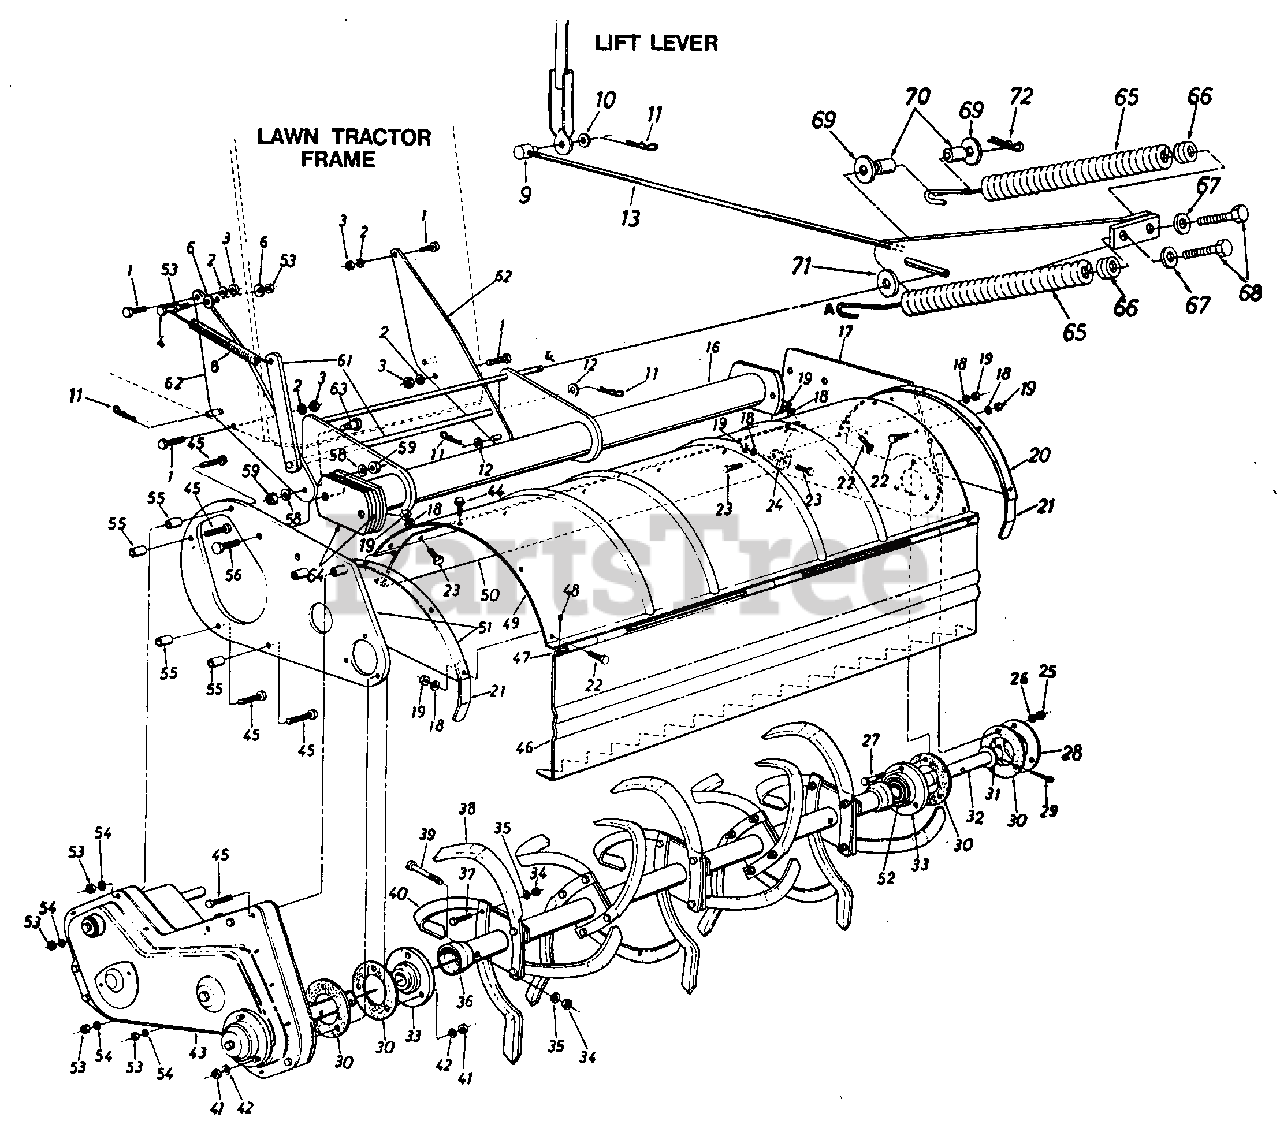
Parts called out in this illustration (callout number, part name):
1	Hex Bolt 3/8-24 x .88" Lg.
2	L-Wash. 3/8" I.D.-H.D.
3	Hex Nut 3/8-24 Thd.
4	Hex Bolt 1/4-20 x 1.25" Lg.
6	Bell-Wash. 1/4" I.D.
8	Ext. Spring 7.75" Lg.
9	Adjustment Ferrule 1/2-13 Thd.
10	Fl-Wash. .64" I.D. x 1.24" O.D. x .06"
11	Intern. Cotter Pin 1/2" Dia.
12	Fl-Wash 51" I.D. x 1.0" O.D. x .06"
16	Pivot Bracket Assembly
19	Hex Nut 5/16-24 Thd.
23	Hex Bolt 5/16-24 x .62" Lg.
24	Chute Pivot Bracket
25	Hex L-Nut 5/16-18 Thd.
27	Hex Bolt 5/16-18 x 1" Lg. (Grade 5)
30	Gasket for Brg. Housing
31	Fl-Wash. 1.25" I.D. x 2.0" O.D. x .06"
32	Tine Shaft 1.25" Dia. x 6.25" Lg.
33	Bearing Housing w/Bearing
43	Chain Case Ass'y. Comp.
44	Hex TT-Tap Scr. 5/16-18 x .62" Lg.
45	Hex Bolt 1/4-20 x 2.75" Lg.
48	Cotter Pin 1/8" Dia. x 1" Lg.
53	Hex Nut 1/4-20 Thd.
54	L-Wash. 1/4" I.D.*
55	Spacer .28" I.D. x .62" O.D. x .9" Lg.
56	Hex Bolt 1/2-20 x 1.5" Lg.
58	L-Wash. 1/2" I.D.
59	Hex Nut 1/2-20 Thd.
61	Idler Brkt. Support Arm Ass'y.
64	Support Plate
65	Helper Spring
66	Spring Insert
67	Fl-Wash. .34" I.D. x .68" O.D.
68	Hex Bolt 5/16-18 x 3.25" Lg.
69	Fl-Wash. .61" I.D. x 1.5" O.D.
70	Split Spacer .505" I.D. x .57" Lg.
71	Fl-Wash. .631" I.D. x 1.25" O.D.
72	Internal Cotter Pin 3/8" Dia.
